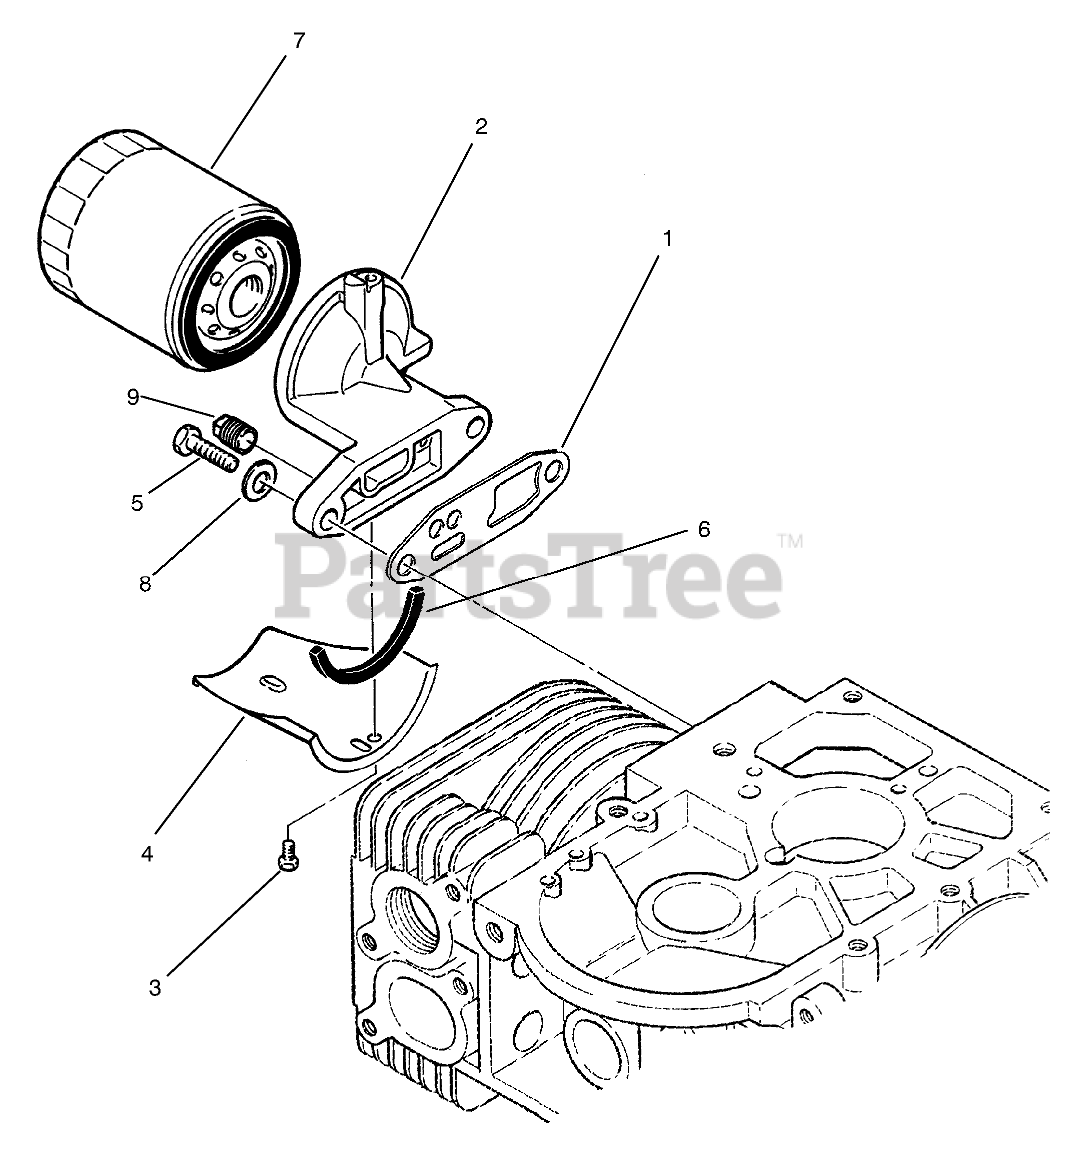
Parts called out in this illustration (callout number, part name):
1	Gasket
2	Adapter
3	Bolt
4	OIL-DRAIN
5	HHCS 5/16-18 X 1
6	OIL-DRAIN SEAL
7	OIL FILTER
8	WASHER
9	Plug
